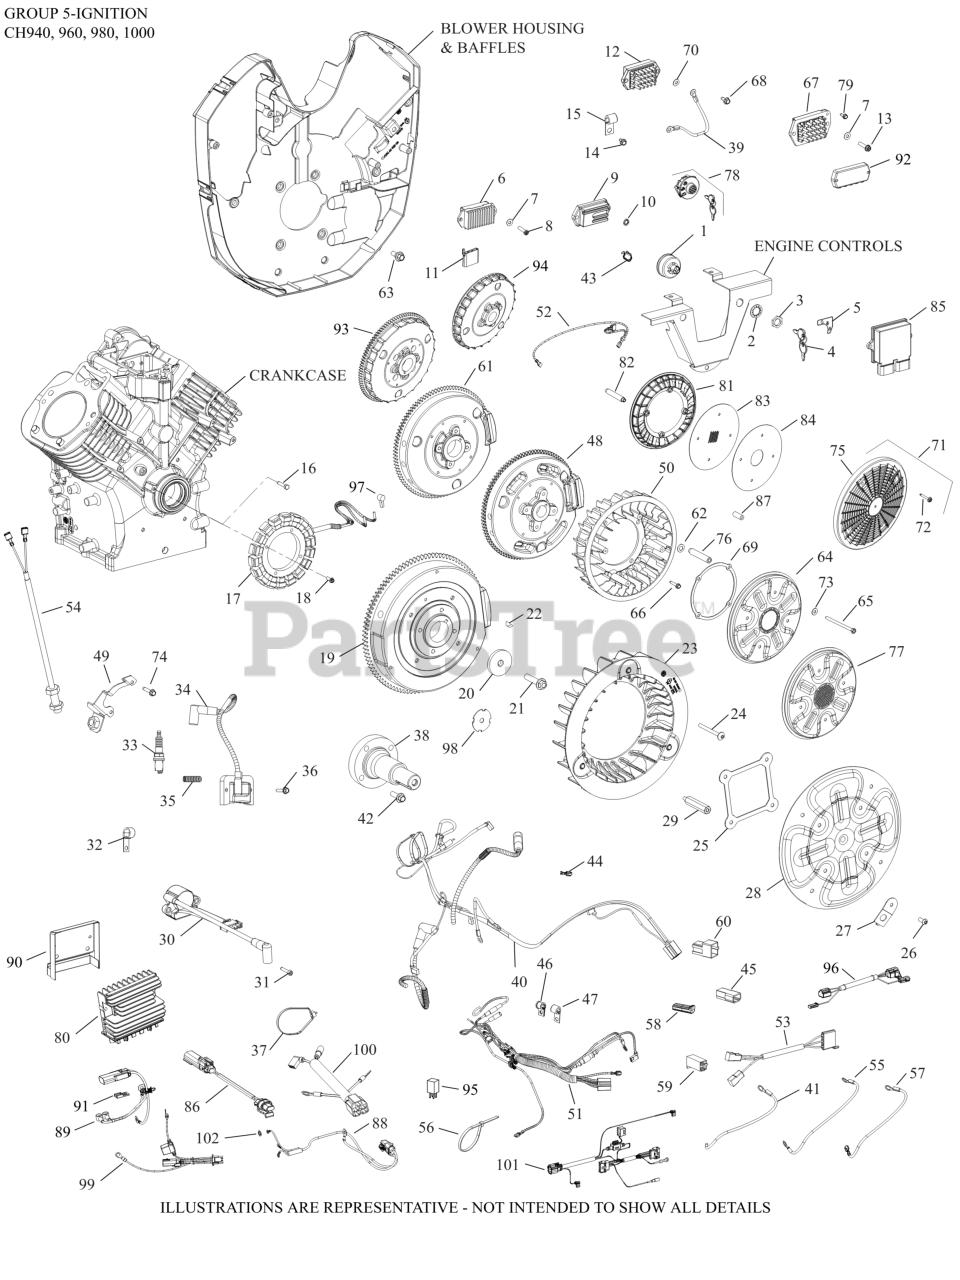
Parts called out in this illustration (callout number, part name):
10	WASHER, INT TOOTH LOCK 1/4"
11	CONNECTOR
13	SCREW, HEX FLANGE HI-LO
15	CLIP, CABLE
17	KIT, 25 AMP STATOR ASSY.
18	SCREW, THREAD FORMING
19	FLYWHEEL ASSEMBLY
20	WASHER, FLAT 13/32"
21	SCREW, FLG M10X1.5X45-USE 25 086 361-S
22	KEY, 3/16" X 5/8"
23	KIT, FAN AND SPACERS
24	SCREW, TRS HD M6X1.0X65
25	STIFFENER, GRASS SCREEN
27	PLATE, GRASS SCREEN WASHER
28	KIT, GRASS SCREEN
29	STUD, GRASS SCREEN
32	CLIP, CABLE
33	PLUG, SPARK
34	MODULE, IGNITION
35	SLEEVE, CORRUGATED
37	TIE, CABLE
39	KIT, GROUND, LEAD
40	HARNESS, WIRING (KEY SWITCH)-(#6217626S)
41	LEAD, B+ TO STARTER SOLENOID
66	SCREW, THREAD THROWING
67	REGULATOR, RECT (20-30AMP, FW W/OVP)
68	SCREW, THREAD FORMING
79	SCREW, THREAD FORMING
